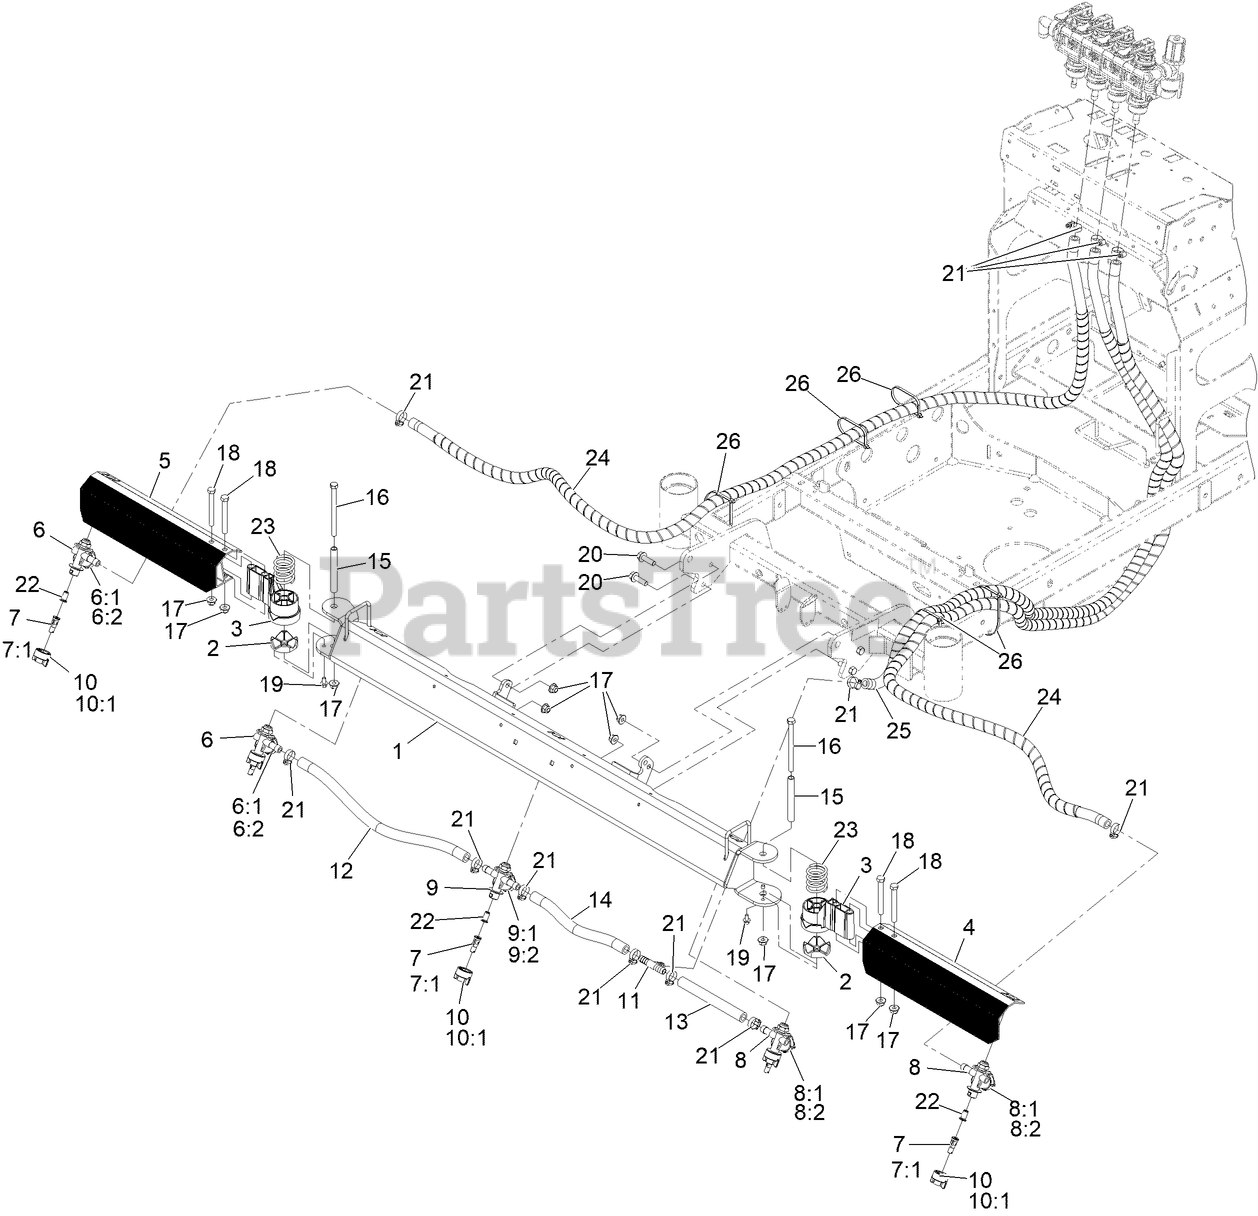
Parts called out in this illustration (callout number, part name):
1	BOOM-CENTER, MAX
2	BOOM-PIVOT
3	HINGE-BOOM
4	BOOM-WING, LH
5	BOOM-WING, RH
6	BODY-NOZZLE, RIGHT
6:1	CAP-SPRAYER NOZZLE
6:2	DIAPHRAGM-SPRAYER NOZZLE
7	NOZZLE-SPRAYER
7	TIP-SPRAY, 015
7	TIP-SPRAY, 02
7	TIP-SPRAY, 025
7	TIP-SPRAY, 03
7	TIP-SPRAY, 04
7	TIP-SPRAY, 05
7	TIP-SPRAY, 06
7	TIP-SPRAY, XRC11020
7:1	SEAT-GASKET
8	BODY-NOZZLE, LEFT
8:1	CAP-DIAPHRAM
8:2	DIAPHRAGM FOR CHECK VALVE
9	BODY-NOZZLE, CENTER
9:1	DIAPHRAGM FOR CHECK VALVE
9:2	CAP-DIAPHRAM
10	CAP-NOZZLE
10:1	SEAT-GASKET
11	FITTING-TEE
12	HOSE-SPRAY
13	HOSE-SPRAY
14	HOSE-SPRAY
15	SPACER-BOOM, PIVOT
16	SCREW-HH
17	Nut-Hex Flange
18	SCREW-HH
19	SCREW-HWH
20	SCREW-HHF
21	CLAMP-HOSE
22	STRAINER-NOZZLE, 50M 5PSI
23	SPRING-COMPRESSION
24	HOSE-SPRAY, WRAPPED
25	HOSE-SPRAY, WRAPPED
26	TIE-CABLE
